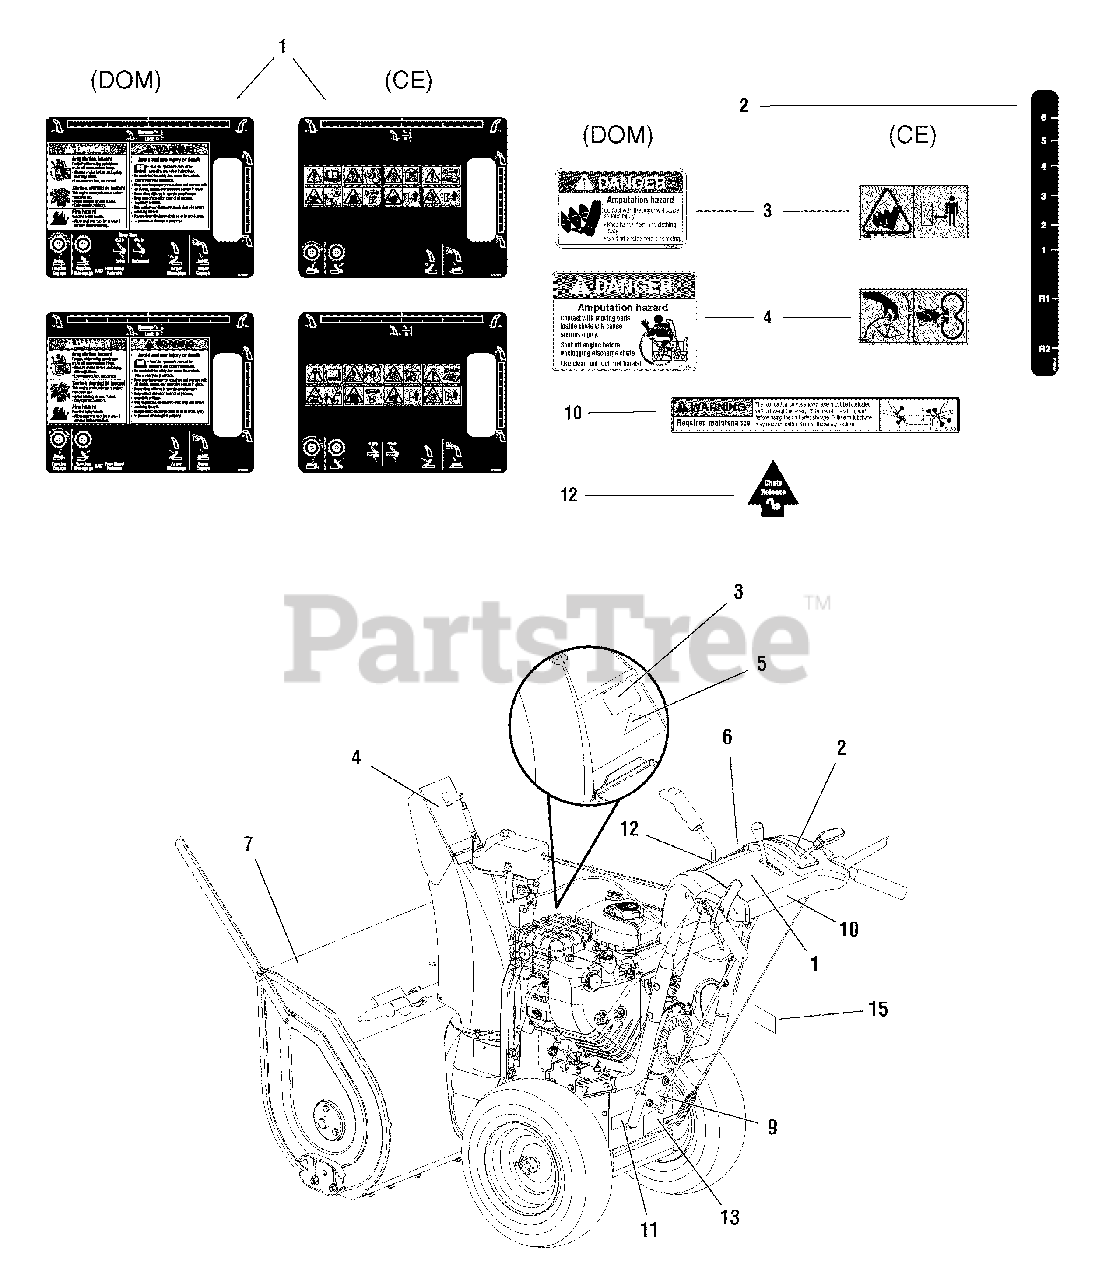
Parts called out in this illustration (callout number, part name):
1	DECAL, Dashboard Standard Drive
1	DECAL, Dashboard EZ Turn
2	DECAL, Shift 1,2,3,4,5,6 R1 R2
3	DECAL, Danger Avoid Injury From Auger
3	DECAL, Impeller Warning
4	DECAL, Danger Amputation Hazard
4	DECAL, Chute Warning
5	DECAL, Opei Certified ANSI
6	DECAL, Snapper, Turtle
7	DECAL, Snapper 1428L, Stripe
7	DECAL, Snapper 1226L, Stripe
7	DECAL, Snapper 1530L, Stripe
7	DECAL, Snapper 1632L, Stripe
7	DECAL, Snapper W/O Turtle
7	DECAL, Snapper, Stripe, 26"
7	DECAL, Snapper, Stripe, 28"
9	DECAL, Over Adjustment of Friction Disc
10	DECAL, Warning Lubrication
11	DECAL, Touch Up Paint Orange, Black, Red
12	DECAL, Chute Release Arrow
13	STICKER, Serial w/Bar Code
15	DECAL, Belt Stretch & Adjustment
